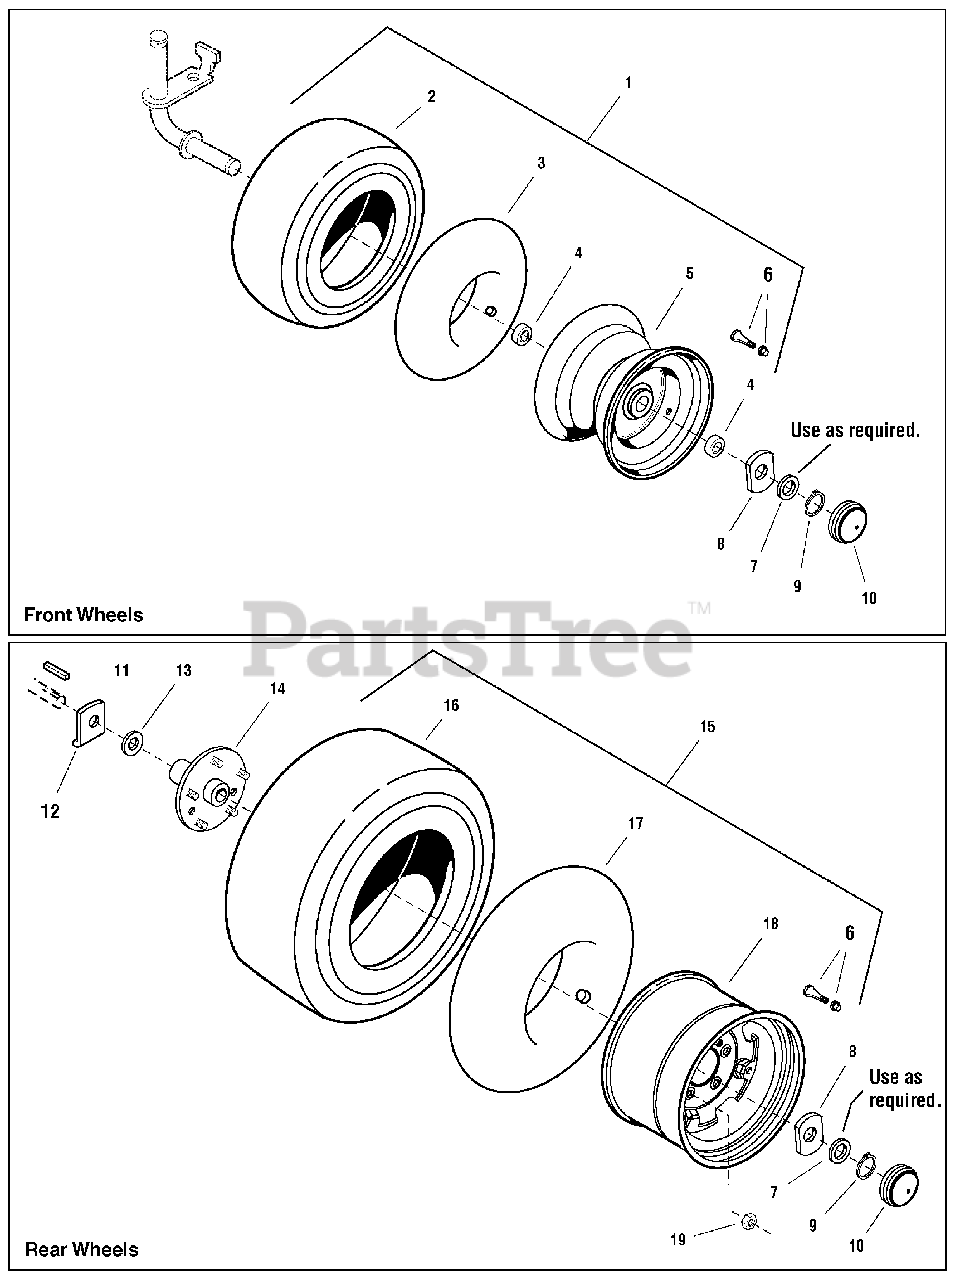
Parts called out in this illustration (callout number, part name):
1	WHEEL & TIRE ASSEMBLY, Front (Includes Ref. 2, 3, 4, 5 & 6)
2	TIRE, 16 x 6-1/2, 8 Super Turf, Front
3	TUBE, Tire 16 x 6 1/2 - 8, Front
4	BEARING, Ball
5	WHEEL, 5-3/8 x 7-15/16, Front
6	VALVE STEM & CAP ASSEMBLY, Air
7	WASHER, 1
8	WASHER, Special, 1 x 2-1/2
9	RING, Shaft
10	CAP, Hub Grey
11	KEY, HI PRO, 1/4 x 2
12	WASHER, Axle Seal "L", 2-1/2 x 2-17/32
13	WASHER, 1
14	PLATE & HUB ASSEMBLY, Rear Wheel
15	WHEEL & TIRE ASSEMBLY, Rear 24" (Includes Ref. 6, 16, 17 & 1
16	TIRE, 24 x 12 - 12 Super Turf, Rear
17	TUBE, Tire 24 x 12 - 12, Rear
18	WHEEL, 8-1/2 x 12, Rear
19	NUT, Hex, 7/16-20, For Wheel Bolt
